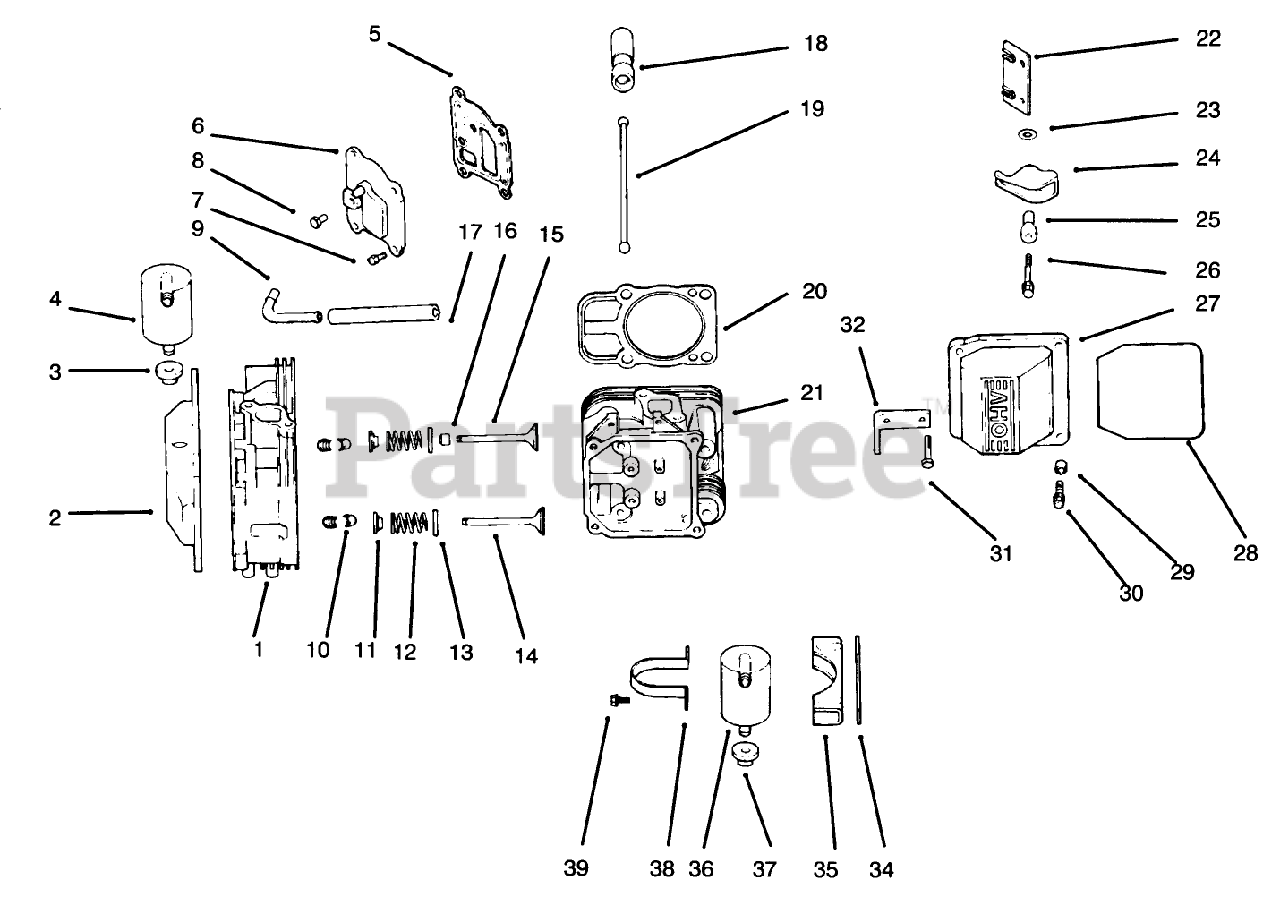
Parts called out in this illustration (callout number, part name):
1	Head ASM-#1 Cylinder
2	Kit-Valve Cover/Breather (Incl. Ref. #3 & 28-30)
3	Grommet-Rubber
4	Kit-Breather (Incl. Ref. #3)
5	Gasket-Breather
6	Cover-Breather
7	Screw
8	Plug
9	Fitting
10	Kit-Retainer
11	Cap-Valve Spring
12	Spring-Valve
13	Retainer-Spring
14	Valve-Exhaust (Std)
15	Valve-Intake (Std)
16	Seal-Valve Stem
17	Hose
18	Lifter-Valve
19	Rod-Push
20	Gasket-Cylinder Head
21	Head ASM-#2 Cylinder
22	Plate-Guide
24	Arm-Rocker
25	Pivot-Rocker Arm
27	Kit-Valve Cover (Incl. Ref. #28-30)
28	"O"Ring
29	Spacer
30	Screw
31	Screw
32	Strap-Lifting
34	Spacer
35	Bracket-Breather Sep
36	Separator-Oil Breather
37	Grommet-Rubber
38	Strap-Breather
39	Screw
